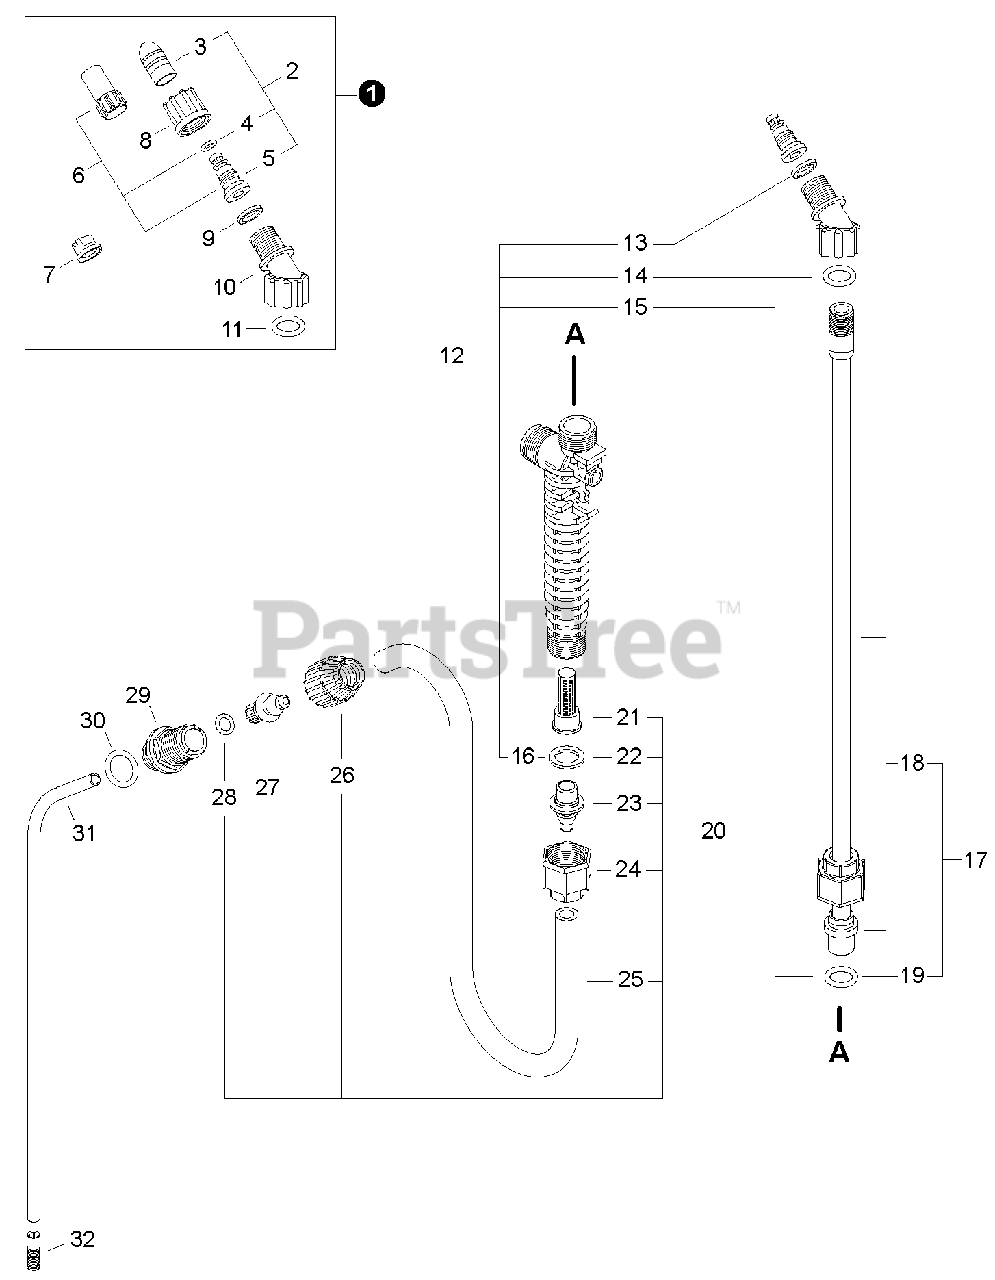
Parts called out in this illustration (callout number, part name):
1	NOZZLE KIT
2	NOZZLE KIT - BRASS
3	CAP, NOZZLE - BRASS
4	O-RING, NOZZLE
5	BODY, NOZZLE
6	NOZZLE KIT - PLASTIC
7	NOZZLE - FLAT FAN
8	NUT, NOZZLE
9	GASKET, NOZZLE
10	ELBOW, NOZZLE
11	O-RING, ELBOW
12	WAND GASKET KIT
13	GASKET, NOZZLE
14	O-RING, ELBOW
16	GASKET, ADAPTER
17	SPRAY WAND ASSY
18	WAND, SPRAYER
20	HOSE KIT
21	FILTER, SPRAY GUN
22	GASKET, ADAPTER
23	ADAPTER, HOSE - BLACK
24	NUT, HOSE
25	HOSE - 1210mm -- CLEAR
26	NUT, TANK
27	ADAPTER, HOSE - WHITE
28	O-RING, ADAPTER
29	OUTLET, TANK - 15/16
30	O-RING, TANK OUTLET
31	TUBE, OUTLET 16-1/4"
32	FILTER, OUTLET
